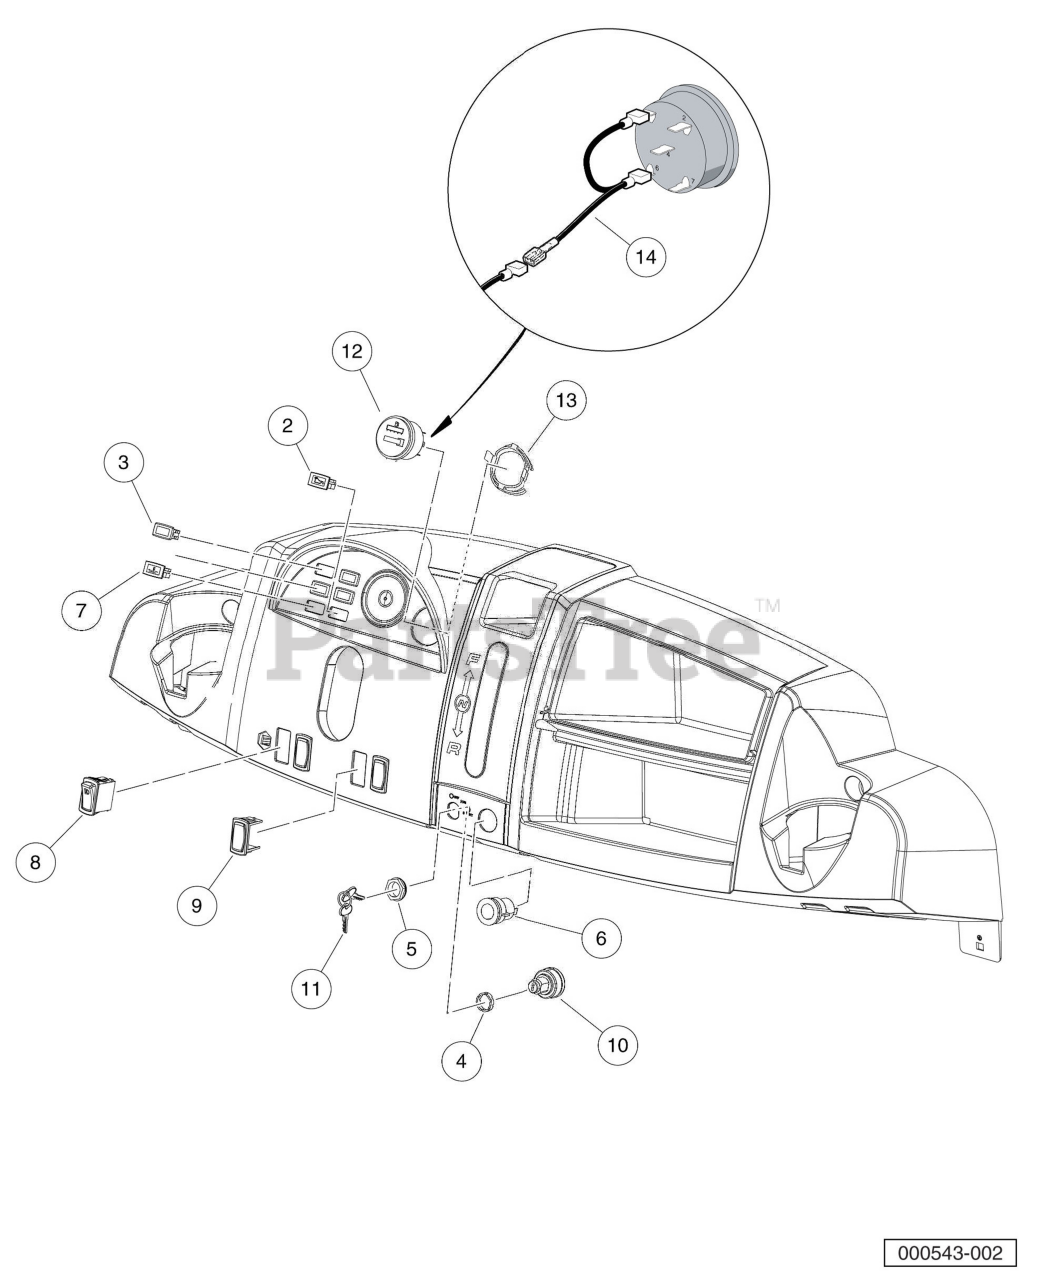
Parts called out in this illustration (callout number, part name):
1	Instl, Elec Sys, Restyle Diesl
2	Light, Oil.
3	Plug, Hole
4	Spacer, Keyswitch.
5	Nut, Key Switch.
6	Receptacle, Accessory
7	Light, Indicator, Coolant Temp
8	Switch, Rocker, Light.
9	Cover, Hole, Switch, Rocker
10	Keyswitch, 12v, Diesel
11	KEYSET, DIESEL AWD
12	Gauge Fuel-hour Sep Gnd
13	Clip, Meter, Round
14	Asm Wire Meter F-h Jumper
